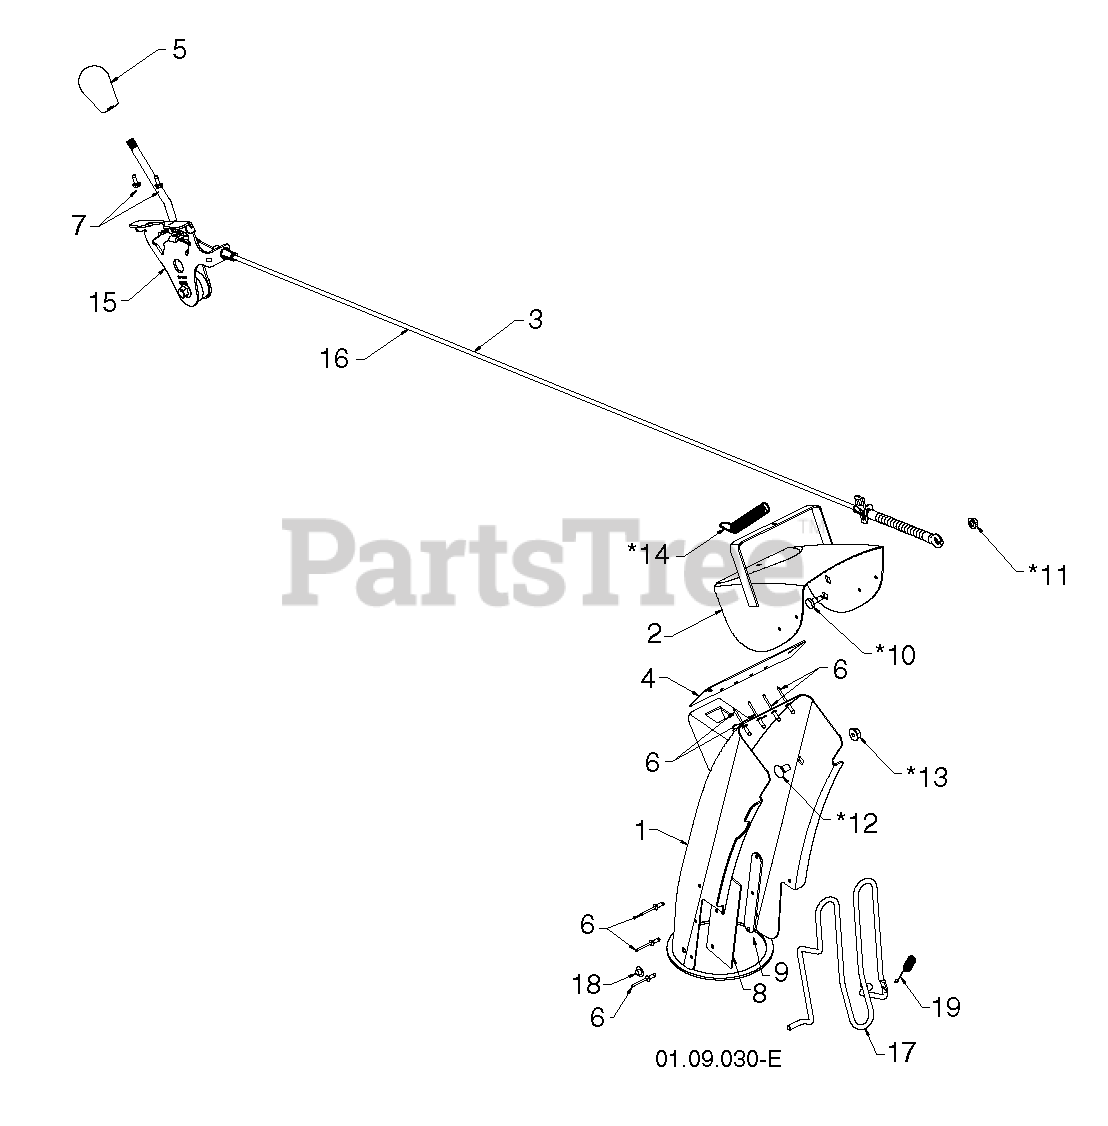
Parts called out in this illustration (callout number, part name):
1	ASM.CHUTE/DEFLECTOR.668
3	CONTROL.ASM.DEFLEC.BLK.BOWDEN
5	KNOB.OVERMOLD.DS.HUSQVARNA/BLK
10	BOLT, SHOULDER
11	NUT.HEX.FLANGE.1/4
12	BOLT CAR BLK 5/16-18 X 5/8
13	NUT.LOCK.5/16-18
14	SPRING.DEFLECTOR.REM.CHUTE
15	RP CNTRL.HEAD.ASSEM.DEFLECTOR
16	RP CABLE.DEFLECTOR.BOWDEN
17	ROD.GUARD.CHUTE (2 2)
18	NUT
19	SPRING.CHUTE.GUARD
